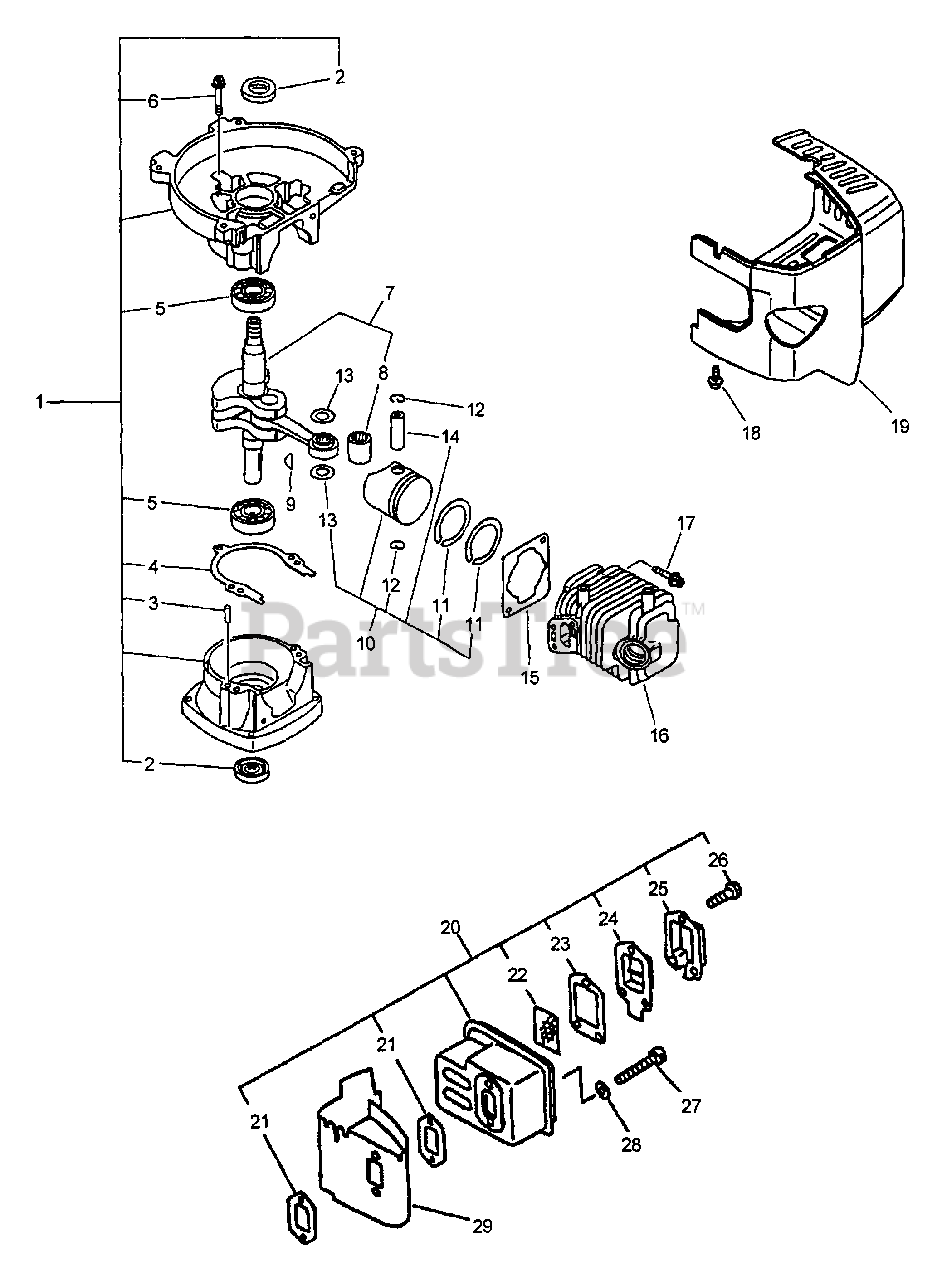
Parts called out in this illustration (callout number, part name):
1	CRANKCASE KIT
2	SEAL, OIL 12
3	PIN, LOCATING 4
4	GASKET, CRANKCASE
5	BEARING, BALL - 6201 C3
6	BOLT 5×28
7	CRANKSHAFT ASSY
8	BEARING, NEEDLE
10	PISTON KIT
11	RING, PISTON
12	RING, SNAP
13	WASHER, THRUST
14	PIN, PISTON 8
15	GASKET, CYLINDER
16	CYLINDER
17	BOLT 5×22
18	SCREW 4×18
19	COVER, CYLINDER
20	MUFFLER ASSY
21	GASKET, EXHAUST
22	SCREEN, SPARK ARRESTER
23	GASKET, EXHAUST
24	GUIDE, EXHAUST
25	GUIDE, EXHAUST - INNER
26	SCREW 4×10
27	BOLT M5×50
28	WASHER, FLAT 5.5×10×0.8
29	COVER, MUFFLER
